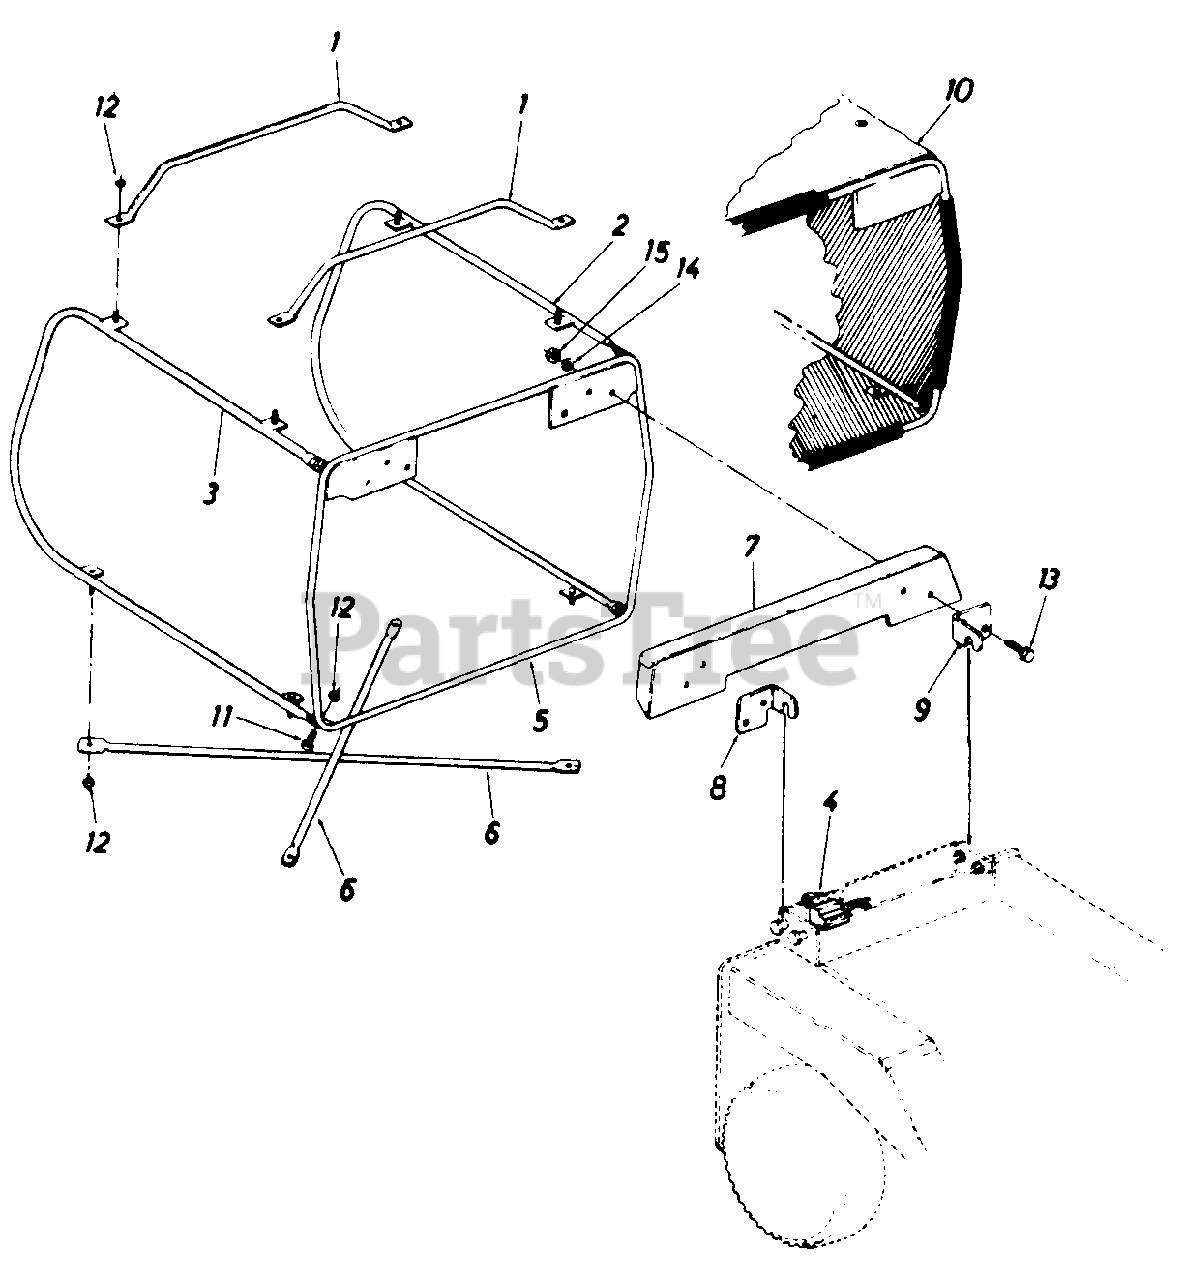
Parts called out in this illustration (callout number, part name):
1	Catcher Handles
2	Catcher Side Frame Ass'y L.H.
3	Catcher Side Frame Ass'y. R.H.
4	Safety Switch
5	Catcher Frame Ass'y.
6	Bottom Cross Brace
7	Dust Cover
8	Hinge-R.H.
9	Hinge L.H.
10	Grass Bag
11	Hex Scr. 1/4-20 x .62" Lg.
12	Hex Gent. L Nut 1/4 20 Thd.
13	Hex Sems Scr. 5/16-18 x 1.OO" Lg
14	LWash. 5/16 Scr.
15	Hex Nut 5/16-18 Thd
